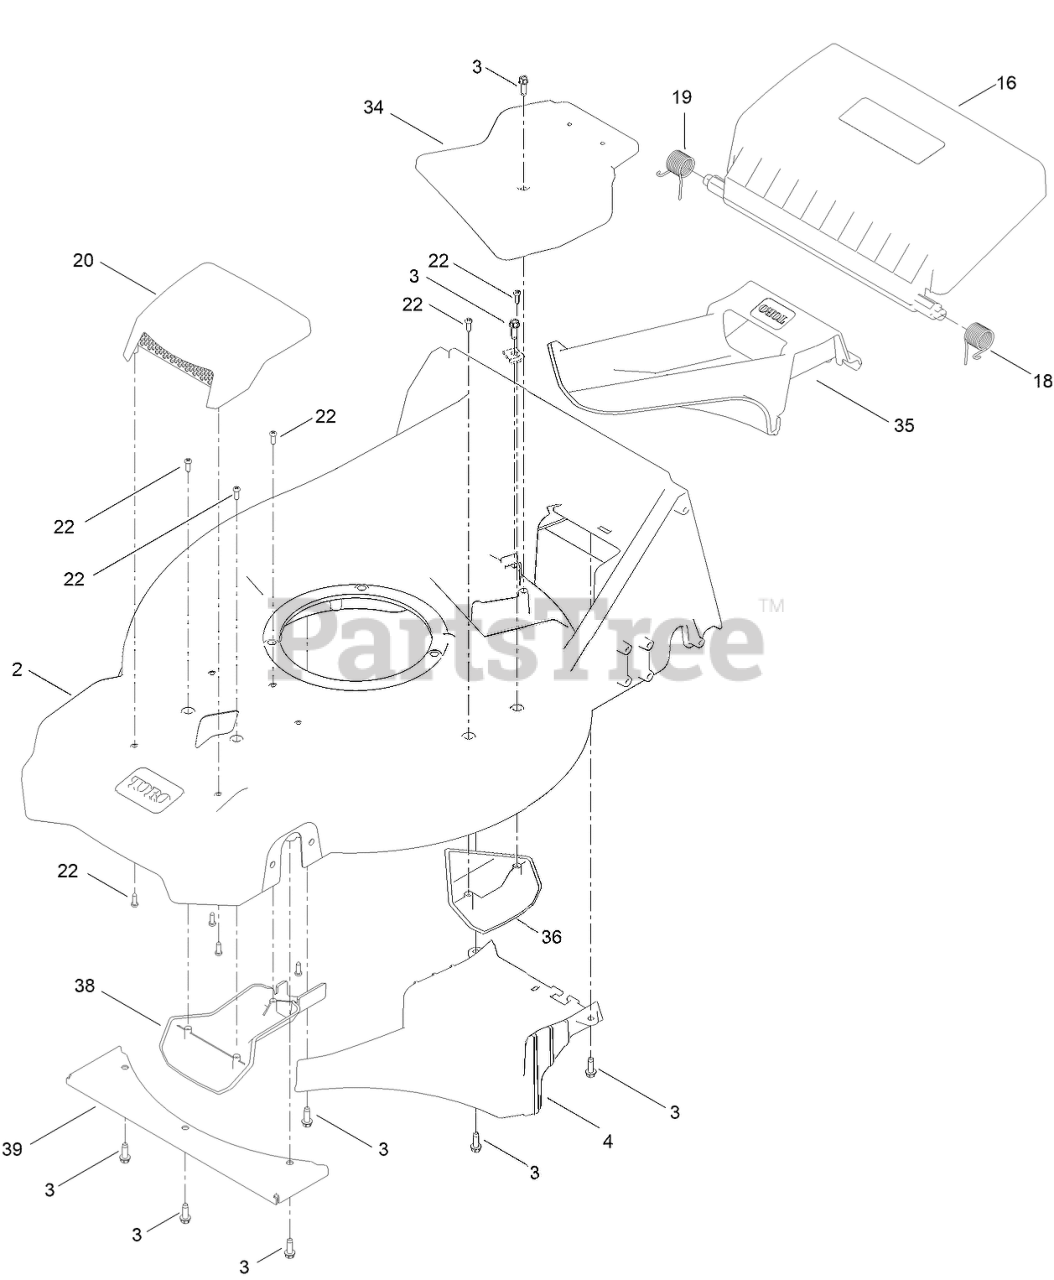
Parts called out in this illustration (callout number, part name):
2	DECK-CAST, 21"
3	SCREW-HWHTF
4	RAMP-DISCHARGE
16	ASM-REAR DOOR, IN MOLD
18	SPRING-TORSION, LH
19	SPRING-TORSION, RH
20	ASM-COVER, TOP INTAKE
22	SCREW-PLASTIC, PPH
34	COVER-BELT, TOP
35	PLUG-MULCH
36	KICKER-HOUSING
38	COVER-INTAKE, BOTTOM
39	PLATE-COVER, CE
